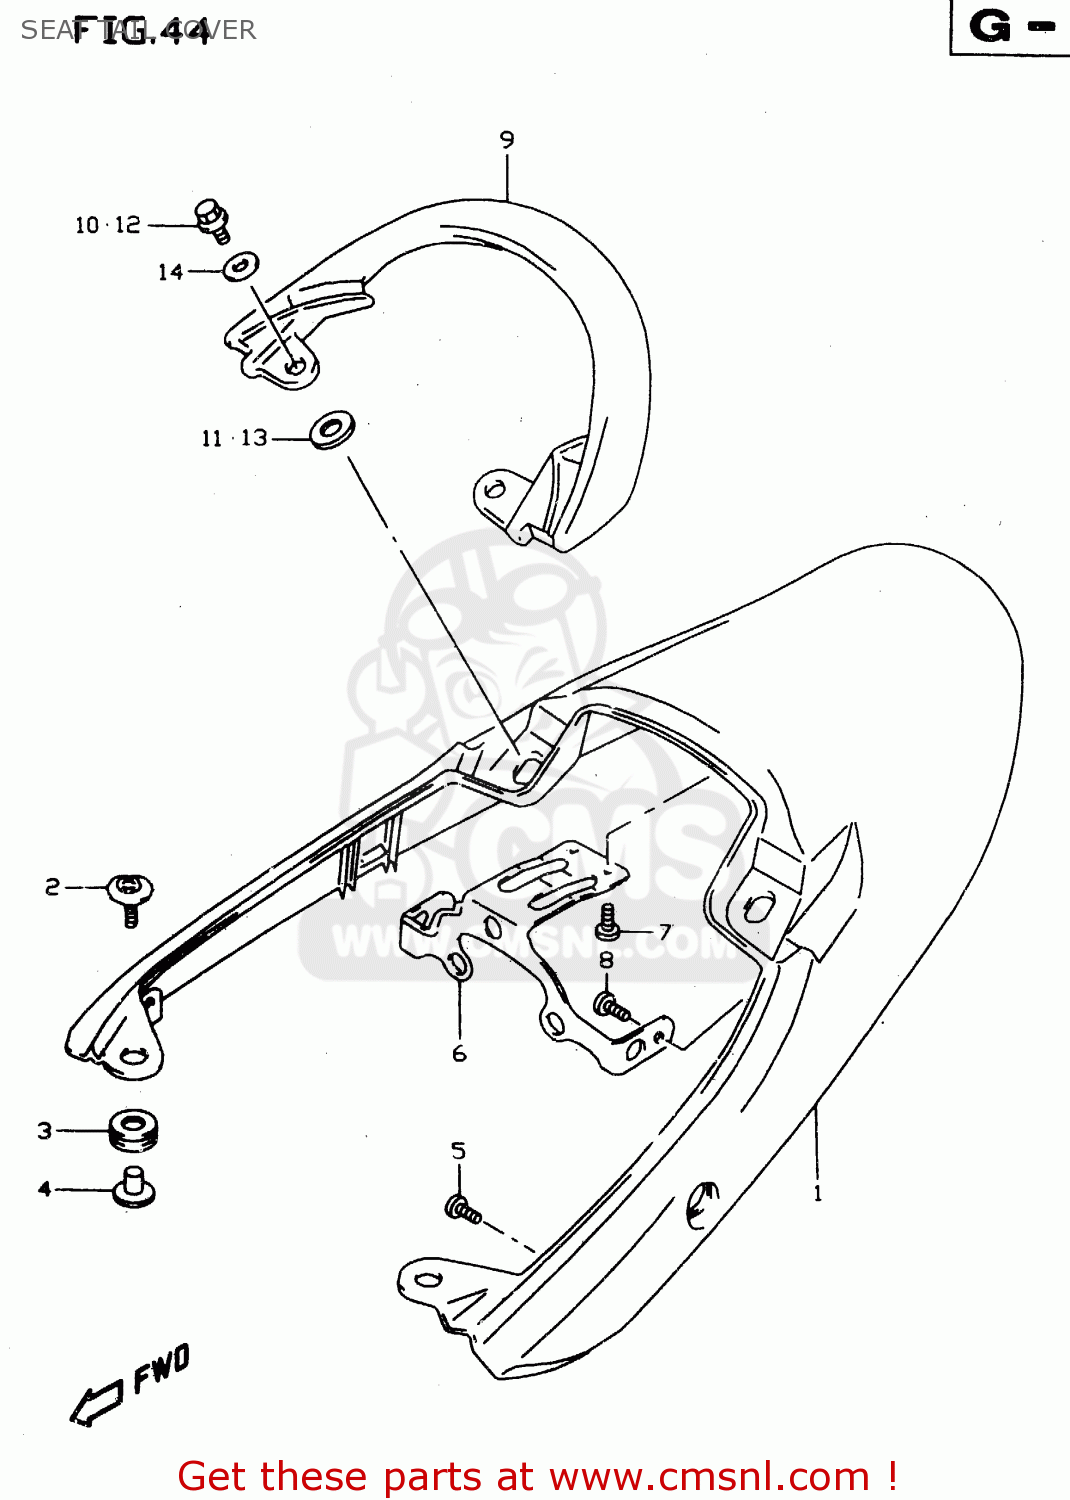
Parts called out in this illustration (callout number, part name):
1	COVER,SEAT TAIL
2	SCREW
3	CUSHION
4	SPACER,SEAT TAIL COVER FR
5	SCREW
6	BRACKET,RR COMBINATION LAMP
7	SCREW
8	SCREW
9	HANDLE,PILLION
10	BOLT
11	CUSHION
12	BOLT
13	CUSHION,RIDER HNDL(17X24X1.5)
14	WASHER(8.5X24X2.3)
